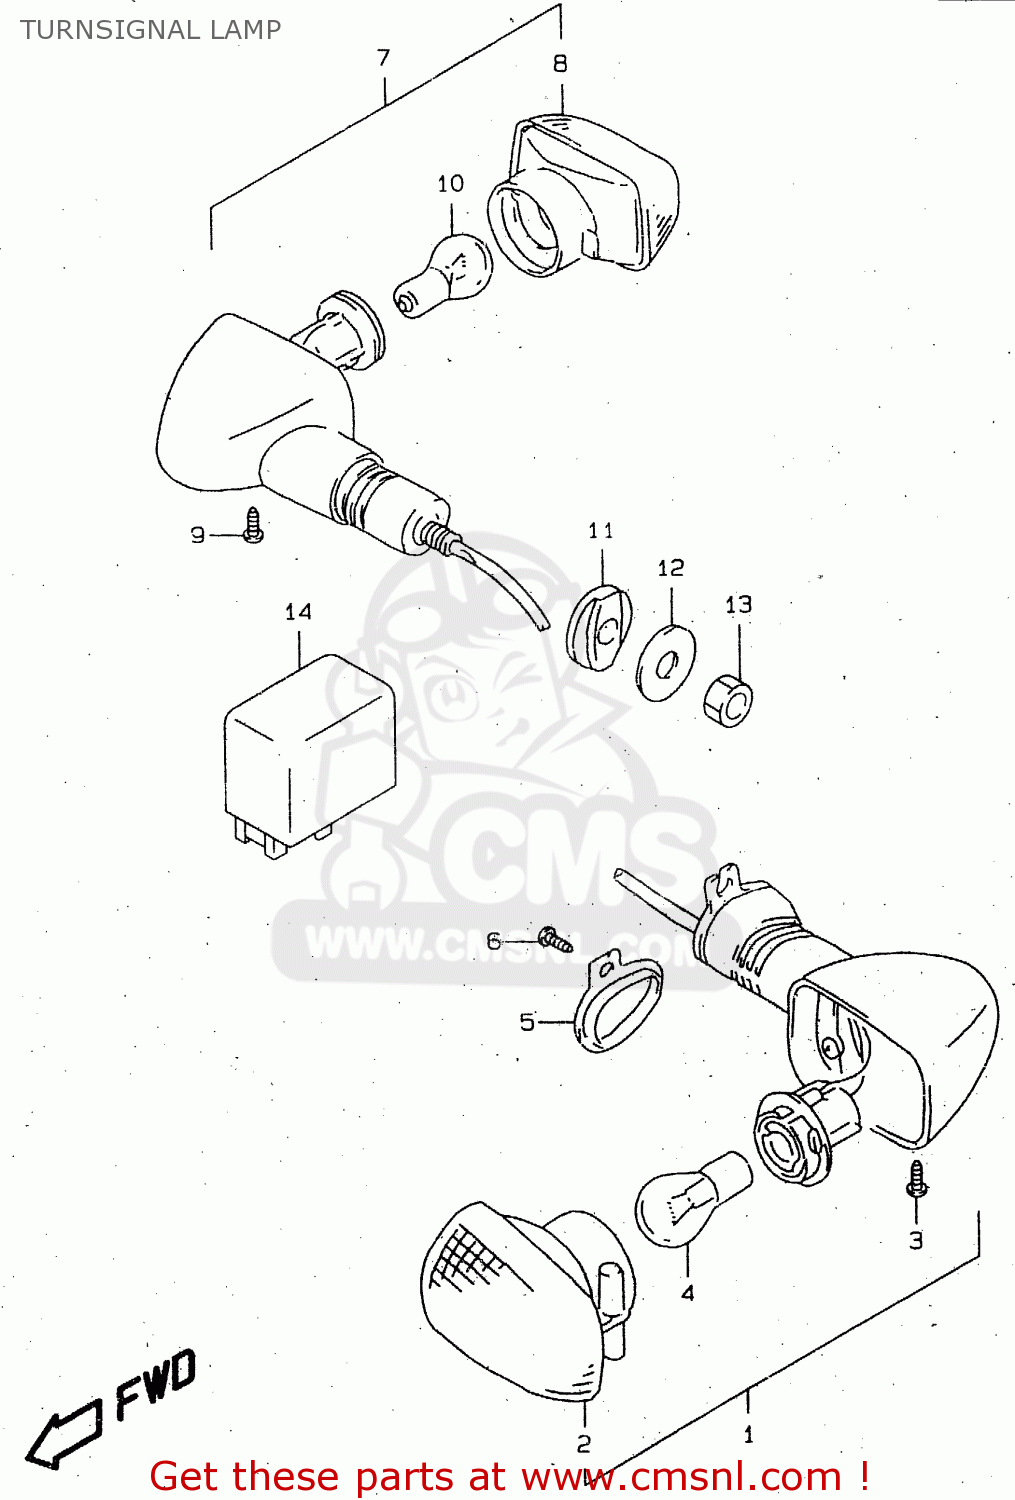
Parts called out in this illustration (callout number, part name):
1	LAMP ASSEMBLY,FRONT TURN SIGNAL
2	LAMP UNIT
3	SCREW
4	BULB(12V21W)
5	PLATE,FR TURNSIGNAL LAMP
6	SCREW
7	LAMP ASSY,RR TURNSIGNAL,R
8	LAMP UNIT
9	SCREW
10	BULB(12V21W)
11	SPACER,RR TURNSIGNAL
12	WASHER(10.5X30X2.3)
13	NUT
14	RELAY ASSY,TURNSIGNAL LAMP
